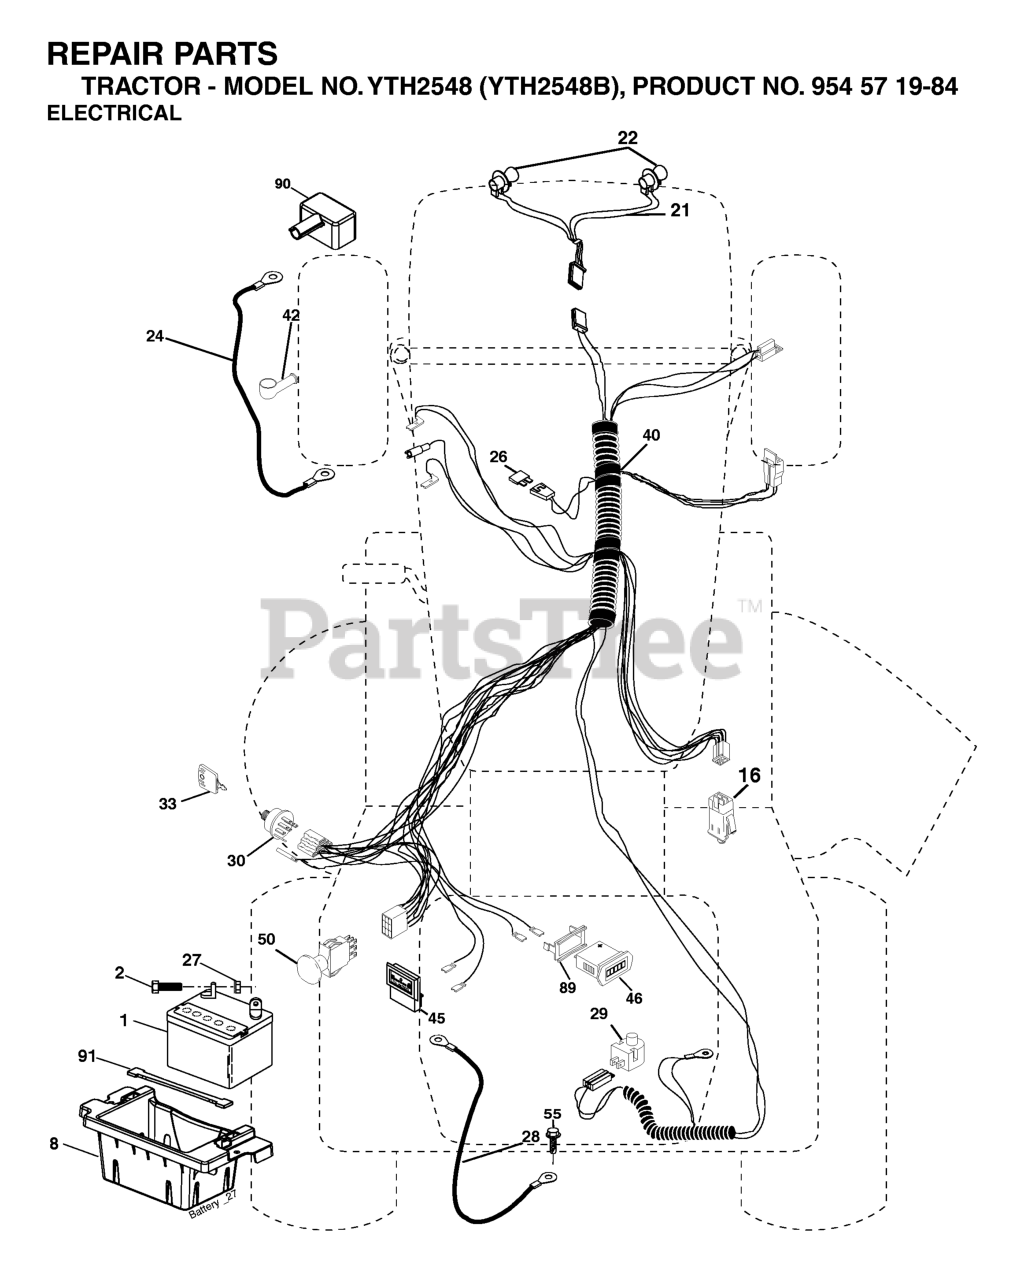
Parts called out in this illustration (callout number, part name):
1	BATTERY 12V .35 AMP
2	BOLT.HEX.1/4.X.3/4.DICHROMATE
8	BOX.BATTERY.MOUNT.FRONT.LT
16	SWITCH INTERLOOK PUSH-IN
21	HARNESS ASSY LIGHT
26	FUSE 20AMP
27	NUT
28	CABLE GROUND 6 GA 21" 90T BLK
29	RP.SWITCH.PLUNGER.NC.GRAY
30	IGNITION SWITCH
33	KEY MLD GEN DELTA
42	COVER.TERMINAL.RED
46	HOUR METER
50	RP.PTO.SWITCH.8 TERMINAL.BLACK
55	Screw 5/16-18 x 1/2 Hex, Self Tapping 5/16-18 x 1/2
89	BRACKET SNAP-IN HOURMETER
90	COVER TERMINAL
91	STRAP.BATTERY.MOUNT.FRONT(2 2)
